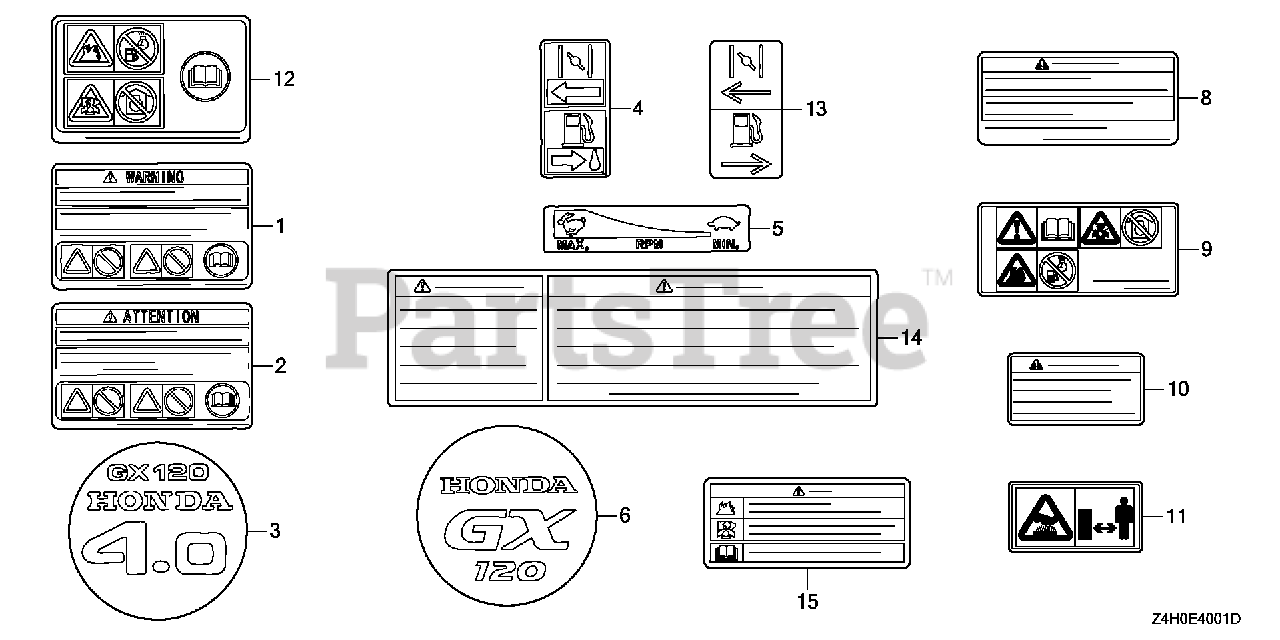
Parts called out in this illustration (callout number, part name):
8	MARK, OPERATOR CAUTION (FRENCH)(MADE IN THAI)
9	MARK, OPERATOR CAUTION (PICTOGRAPH)
10	MARK, EX. CAUTION (FRENCH)
11	MARK, EX. CAUTION (PICTOGRAPH)
14	LABEL, SPARK WARNING
